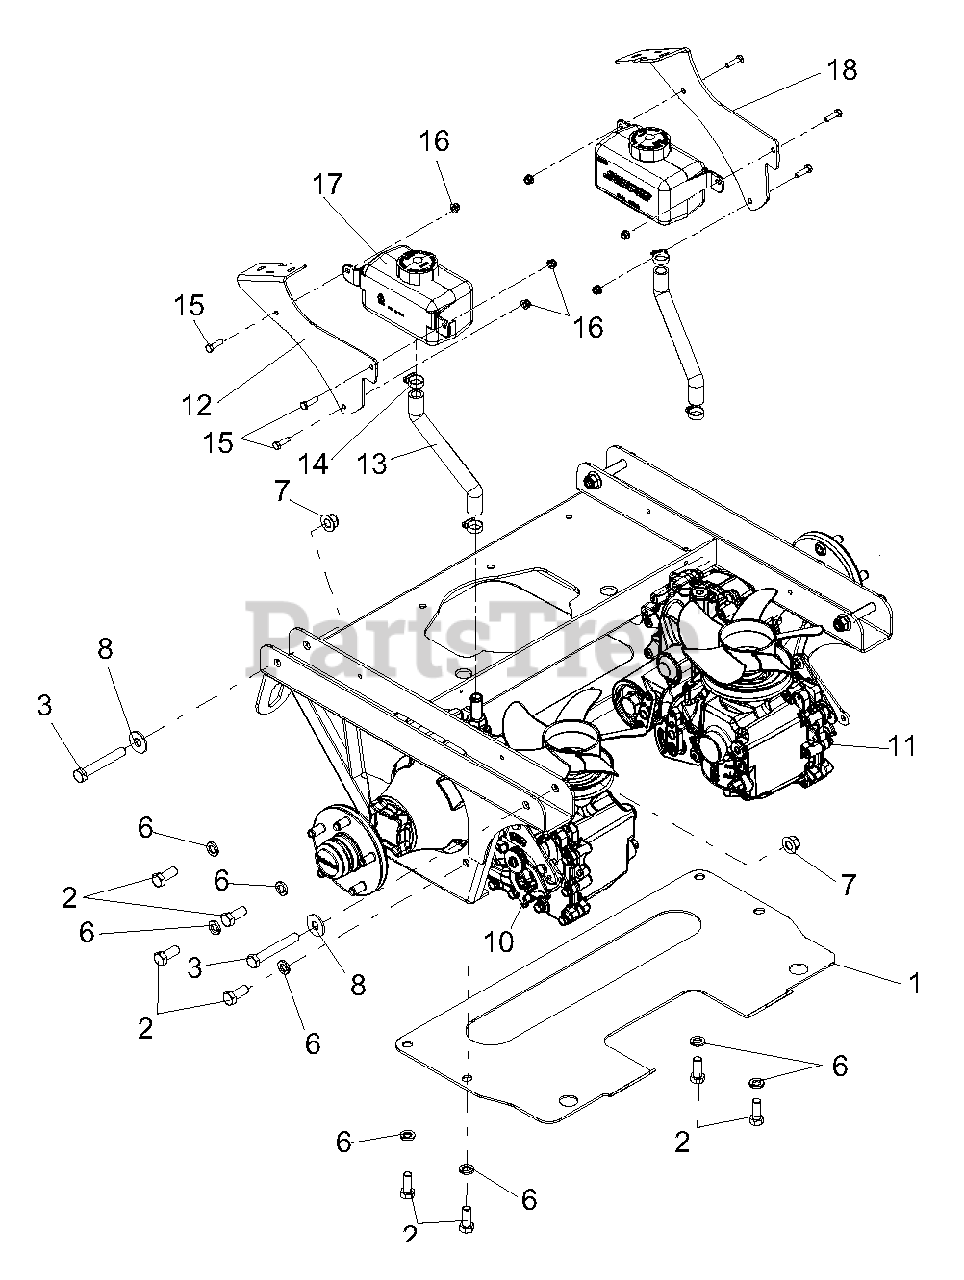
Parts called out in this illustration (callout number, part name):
1	PLATE, TRANSMISSION SKID
2	BLT-HEX .50-13X1.25 GR5 YWZC
3	BLT-HEX .50-13X3.50 GR5 YWZC
6	WSHR-LK .50X.125 REG YWZC
7	NUT-LK-NYL-FLG .50-13 YWZC
8	WSHR-FL-STL.563X1.38X.109YWZC
10	TRANS, R.H. HG ZT-5400
11	TRANS, LH HG ZT-5400
12	BKRT, RH CANISTER MTG (CARB)
13	HOSE, HYDRO OVERFLOW
14	CLAMP, .88 DIA HOSE
15	BLT-HEX .25-20X1.00 GR5 YWZC
16	NUT-LK-NYL-FLG .25-20 YWZC
17	TANK, HYD 1000ML
18	BRKT, LH CANISTER MTG (CARB)
